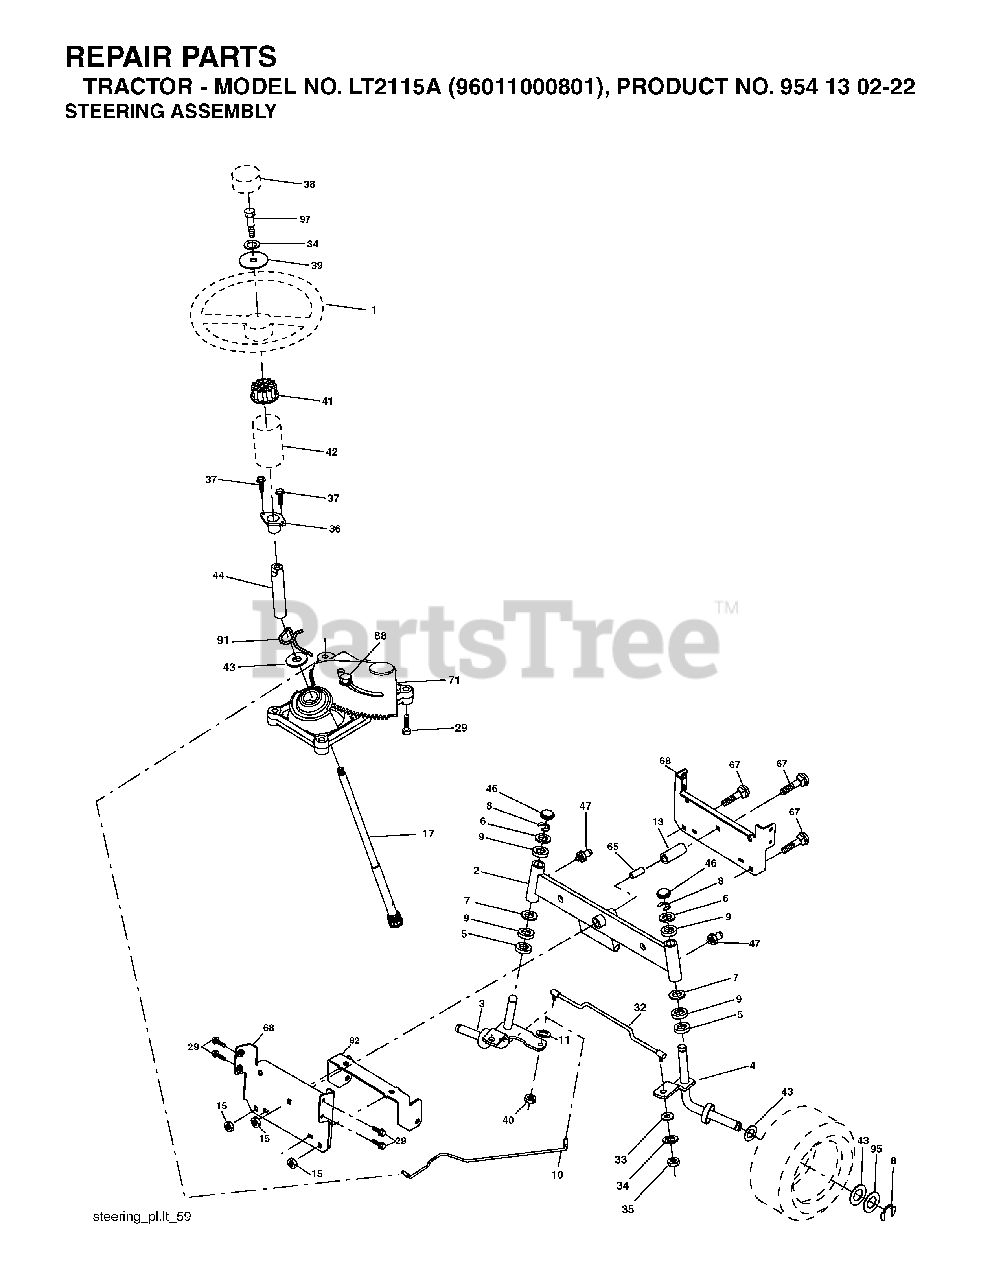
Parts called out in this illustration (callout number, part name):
1	WHEEL.STEERING.PREM.2.BLK
2	AXLE ASM.
3	SPINDLE.ASM.LH.15"TIRES
4	SPINDLE.ASM.RH.15"TIRES
8	RING CLIP
9	BRNG T
10	DRAGLINK.15".TIRES.2001
11	WASHER, LOCK 3/8
13	TUBE, PIVOT AXLE
15	NUT
17	SHAFT STEERING SPLINE
29	SCREW, 3/8-16X3/4
33	WASHER M
34	LOCKWASHER
35	NUT, CROWNLOCK
36	BUSHING, STEERING
38	INSERT.CAP.STRG.WH.BLACK
39	WASHER.11/32
40	NUT CROWNLOCK 3/8-24
41	STEERING WHEEL ADAPTOR
42	BOOT.STEERING.SHAFT.BLACK
44	EXT, STEERING SHAFT
46	CAP.SPINDLE
47	FITTING.GREASE.TAPERED
65	SPACER BRACE AXLE
67	BOLT CARRIAGE
68	BRACE.AXLE.15"TIRES
71	STEERING ASM
82	BRACKET
88	BOLT, SHOULDER 7/16-20
91	CLIP.STEERING
95	WASHER.HARDENED
